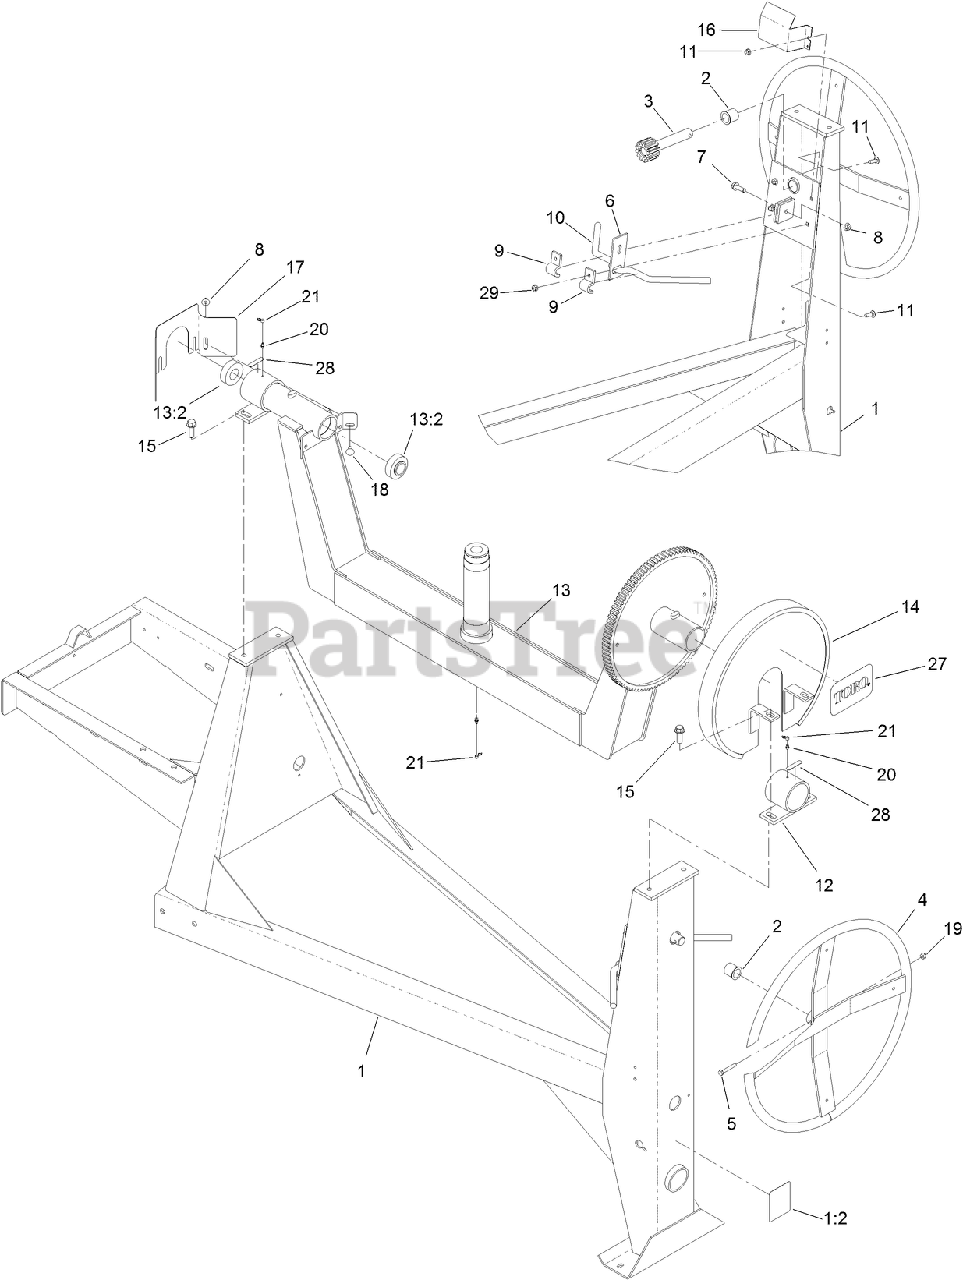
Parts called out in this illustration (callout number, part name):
1	FRAME ASM
1:2	DECAL-SAFETY CHAIN, TOWING
2	BUSHING-NYLON
3	SHAFT-TILT
4	HANDWHEEL
5	SCREW-HH
6	DOG-BRAKE
7	SCREW-HHF
8	NUT-HF, NI
9	BRACKET-HANDLE
10	HANDLE-BRAKE
11	BOLT-CARR
12	TRUNNION
13	YOKE ASM
13:2	BEARING
14	GUARD-BRAKE, UPPER
15	SCREW-HWH
16	GUARD-BRAKE, LOWER
17	GUARD-PINION
18	SCREW-CARR
19	NUT-LOCK, NI
20	FITTING-GREASE
21	CAP-PLUG
27	DECAL
28	DECAL-GREASE
29	NUT-HF, NI
